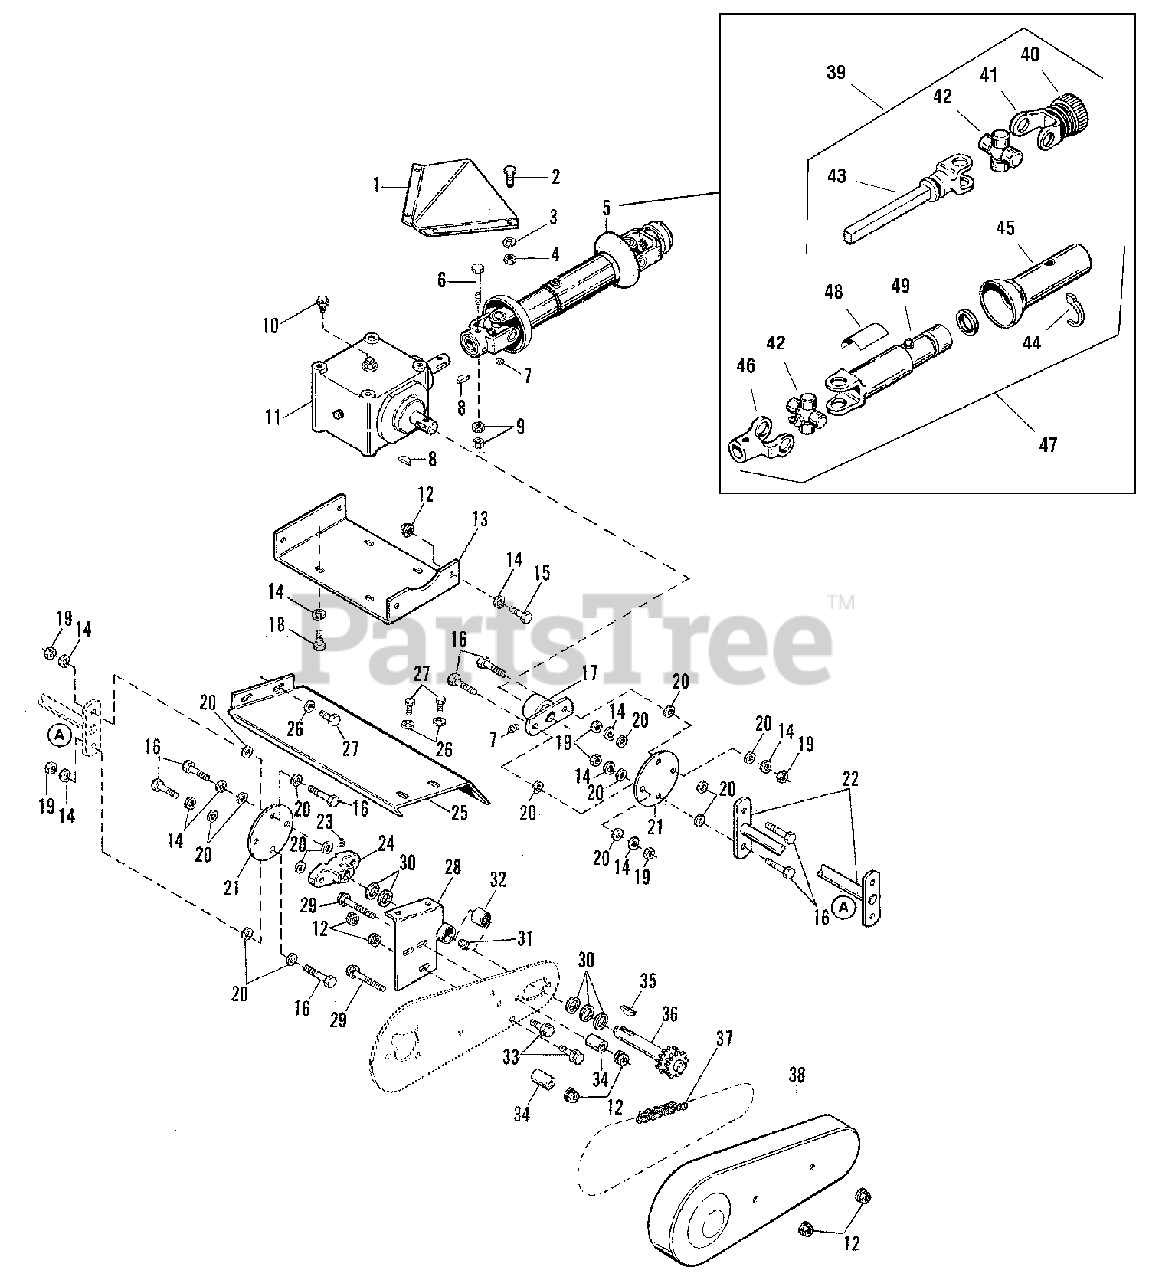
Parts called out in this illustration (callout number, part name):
2	CAPSCREW, Hex Head, 5/16-18 x 5/8
3	LOCKWASHER, 5/16
4	NUT, Hex, 5/16-18
5	DRIVE SHAFT ASSEMBLY (Incl. Ref. Nos 39-47)
6	CAPSCREW, Hex Head, 1/4-20 x 3
7	SETSCREW, Square Head, 5/16-18 x 5/8, G8
8	KEY, Hi-Pro #HP708, 1/4
9	NUT, Hex, Lock,1/4-20
10	PLUG, Socket Head
11	GEAR BOX ASSEMBLY, Right Angle (Incl. Ref. No. 10) (See Single-Stage Snowthrower, 46 - Gear Box Assembly)
12	NUT, Hex Flange Whiz Lock, 3/8-16
13	BRACKET,
14	WASHER, Lock, 3/8
15	CAPSCREW, Hex Head, 3/8-16 x 7/8
16	CAPSCREW, Hex Head, 3/8-16 x 1-1/4
17	COUPLER ASSEMBLY, Drive
18	CAPSCREW, Hex Head, 3/8-16 x 3/4
19	NUT, Hex, 3/8-16
20	WASHER, Special, 3/8
22	SHAFT ASSEMBLY, Drive
23	SETSCREW, Hex Socket, 3/8-24 x 3/8
24	FLANGE, Drive Shaft
25	COVER ASSEMBLY, Drive Shaft
26	WASHER, 5/16
27	CAPSCREW, Hex Head, Taptite, 5/16-18 x 1/2
28	SUPPORT ASSEMBLY, w/Bearings (Incl. Ref. No. 32)
29	CAPSCREW, Hex Head, Whiz Lock, 3/8-16 x 2-3/4
30	WASHER, Hardened, Thrust
31	FITTING, Grease, 1/4
32	BEARING, Needle
33	CAPSCREW, Hex Head, Whiz Lock, 3/8-16 x 1
35	KEY, Woodruff #9
36	SHAFT ASSEMBLY, (Drive, Chain)
37	CHAIN, Roller, #40 32" 64 Pitch
38	GUARD, Chain
39	JOINT & SHAFT ASSEMBLY, w/guard (Incl Ref. Nos. 40-43)
40	SPRING LOCK KIT
41	YOKE ASSEMBLY, Spring-Lock
42	CROSS & BEARING KIT
43	YOKE & SHAFT ASSEMBLY
44	REPAIR KIT, Nylon
45	GUARD, Outer
47	JOINT & TUBE ASSEMBLY, w/guard (lncl. Ref. Nos. 42,44-46)
48	DECAL, Caution Rotating Shaft
49	YOKE, TUBE & SLIP SLEEVE
